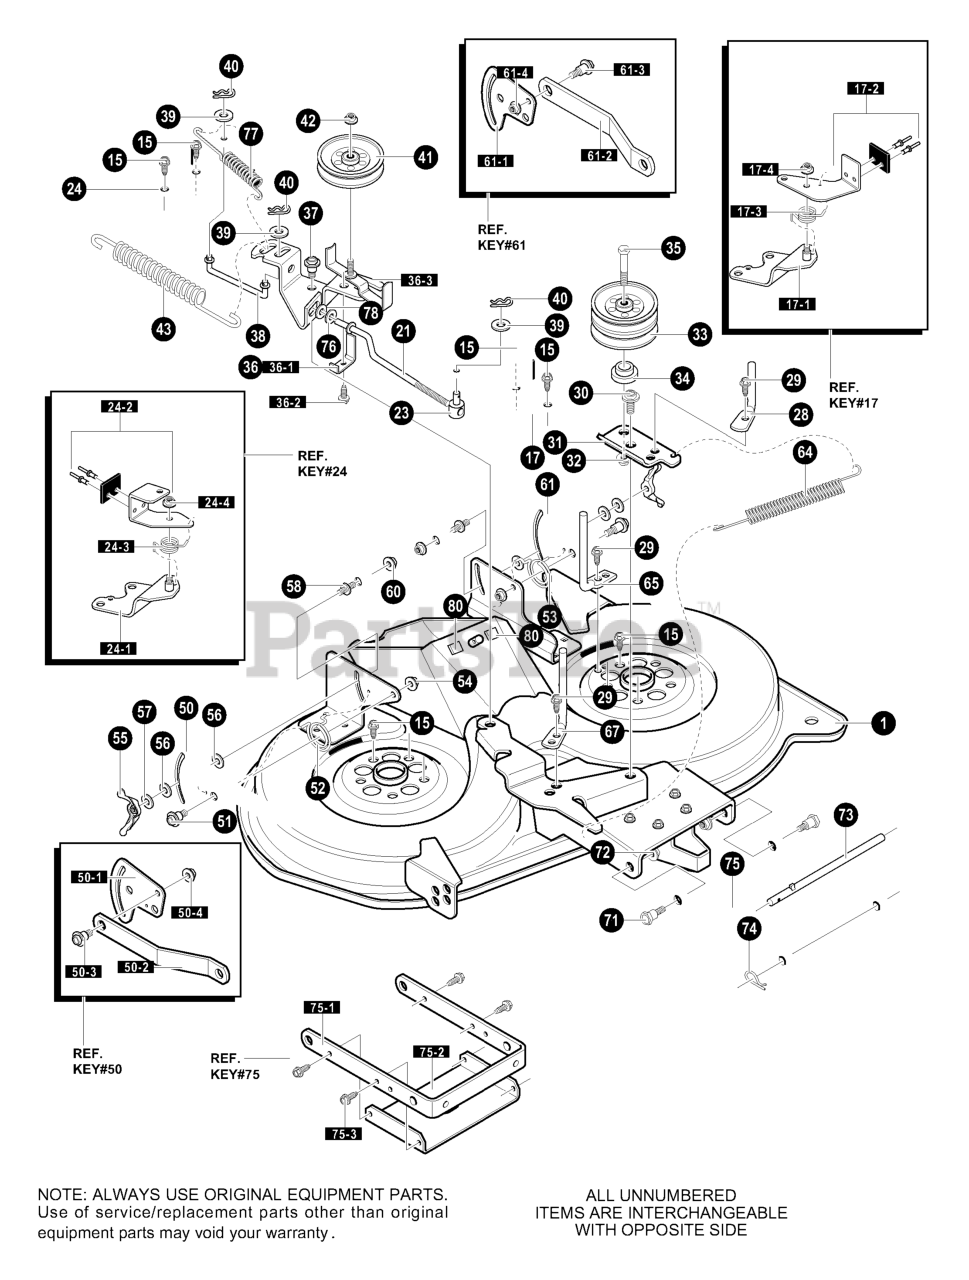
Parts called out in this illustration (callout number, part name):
1	HOUSING, 40" DECK
17	BRAKE ARM ASSEMBLY LH
17-1	BRAKE SUPPORT ASSEMBLY LH
17-2	BRAKE ARM ASSEMBLY LH
17-3	SPRING, TORSION
17-4	NUT, 5/16-18
21	LINK, BRAKE LH
23	NUT, ADJUST
24	BRAKE ARM ASSEMBLY RH
24-1	BRAKE SUPPORT ASSEMBLY RH
24-2	BRAKE ARM ASSEMBLY RH
24-3	SPRING, TORSION
24-4	NUT, 5/16-18
28	GUIDE, BELT
29	SCREW,5/16-18 X .50
30	BOLT, SHOULDER
31	ARM, DOUBLE IDLER
32	NUT, 3/8-16
33	PULLEY,IDLER DOUBLE VEE
35	Screw, 3/8-16 x 3.00
36	IDLER ARM ASSY
36-1	SPRING - GUIDE BELT
36-2	SCREW, 1/4-20X .50
36-3	IDLER ARM ASSEMBLY
37	BOLT., SHOULDER
38	LINK, BRAKE RH
39	WASHER, FLAT .375X.87 INSULATE
40	PIN, HAIR
41	PULLEY, V IDLER 4"
42	NUT,3/8-16
43	SPRING, EXTENSION
50	ASSEMBLY, PLATE,REAR SUS.BRKT.RH
50-1	PLATE - SUSPENSION
50-2	SUSPENSION BRACKET REAR
50-3	BOLT, SHOULDER
50-4	NUT,3/8-16
51	BOLT, SHOULDER
52	SPRING, TORSION RH
53	SPRING, TORSION LH
54	NUT,3/8-16
55	WINGNUT, 5/16-18
56	PAD, FRICTION
57	WASHER
58	PIN, HANGER
60	NUT, 3/8-16
61	ASSEMBLY, PLATE, REAR SUS.BRKT.LH
61-1	PLATE - SUSPENSION
61-2	SUSPENSION BRACKET, REAR
61-3	BOLT, SHOULDER 3/8-16
61-4	NUT,3/8-16
64	SPRING, EXTENSION
65	GUIDE, BELT
67	GUIDE, BELT
71	BOLT, SHOULDER
72	NUT, 3/8-16
73	ROD, HANGER
74	PIN, HAIR
75	ASSEMBLY, BRACKET & STIFFENER
75-1	BRACKET, FRONT SUSPENSION
75-2	STIFFENER
75-3	SCREW, 5/16-18 x 0.75
76	WASHER, FLAT .391X1.00X.125
77	SPRING, EXTENSION
78	WASHER, FLAT .375X.87 INSULATE
80	PAD, ADHESIVE 1.00X1.50X.12
